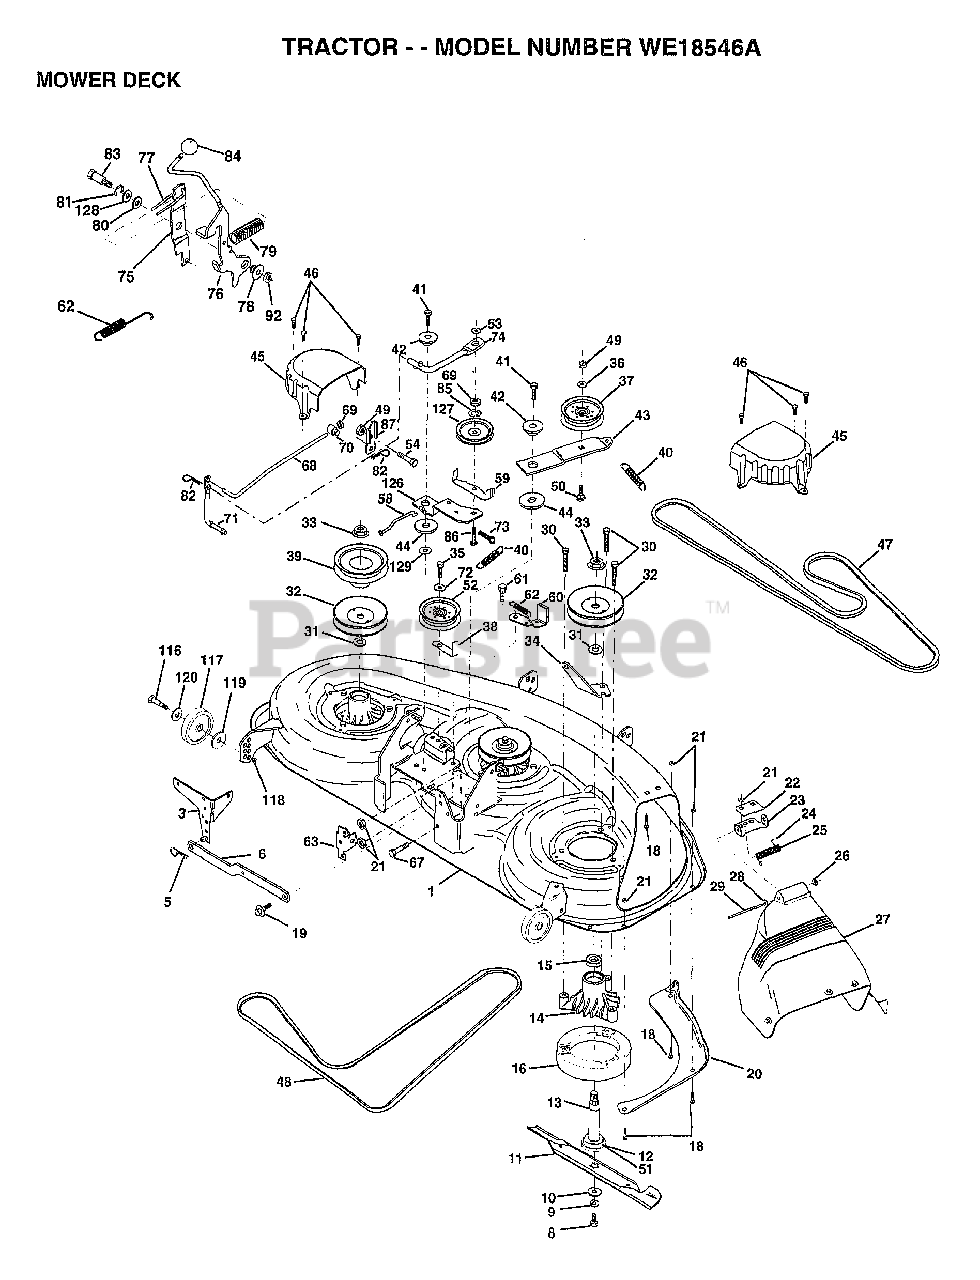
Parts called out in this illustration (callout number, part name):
1	"MOWER ASM 46"""
3	BRKT.ASM.SW.44/50
8	BLADE BOLT
10	WASHER.HARD.BLADE
11	"BLADE.HIGHLIFT46"""
12	BEARING.BALL
13	SHAFT.ASM.W/BRNG
14	HOUSING.MAND.44.V
15	BEARING
16	STRIPPER RND MWR
18	BOLT
19	BOLT SHD 5/16-18
20	BAFFFLE.VORTEX.46
22	STIFFENER BRKT
23	DEFLECTOR BRKT
24	CAP-SLEEVE LT
26	NUT PUSH M
27	SHIELD DEFLECTOR
28	WASHER
29	HINGE ROD
30	"SCREW-THD ROLL,WA"
31	WASHER
32	PULLEY.MAND.36/46
34	ANCHOR.SPRING.46
35	SCREW LT
36	WASHER
37	FLAT IDLER PULLEY
38	"KEEPER BELT,IDLER"
39	PULLEY.DRV.DCK.46
40	"SPRING.SEC.44""VEN"
41	SCREW
42	SPACER RETAINER
43	ARM.IDLER.DECK.46
44	HARDENED WASHER
45	COVER.MANDREL.46
46	SCREW.1/4-20X5/8
47	BELT-V.SEC.46.KEL
48	V BELT MOWER
50	BOLT.3/8-16X1.50
51	WASHER.FELT.
52	"PULLEY IDLER,FLAT"
53	WASHER
54	BOLT
58	"LINK BRAKE, 43"""
59	"GUIDE BELT,46""MOW"
60	ARM ASM BRAKE
61	BOLT.SHOULDER.5/16-18
62	RETURN SPRING
63	"BRKT ROD,CLUTCH"
67	BOLT
69	NUT
70	TRUNION ADJ
71	PIVOT ROD
72	WASHER
73	COTTER PIN
74	LINK CLUTCH
75	CLUTCH ARM SECOND
76	LEVER.ASM.CLUTCH
77	SPRING KEEPER
78	BUSHING
79	SPRING.CLUTCH.MWR
80	WASHER
81	RING
82	RETAINER M
83	SHOULDER BOLT
84	KNOB.RD.7/16-14
85	LOCKWASHER
86	"BOLT CARR, SH"
87	BRACKET.EXTENSION
92	NUT
116	BOLT M
117	WHEEL.GAGE.BLK.PL
118	LOCKNUT
119	WASHER
120	WASHER
127	PULLEY.IDLER.4.25
128	WASHER .T
129	WASHER T
